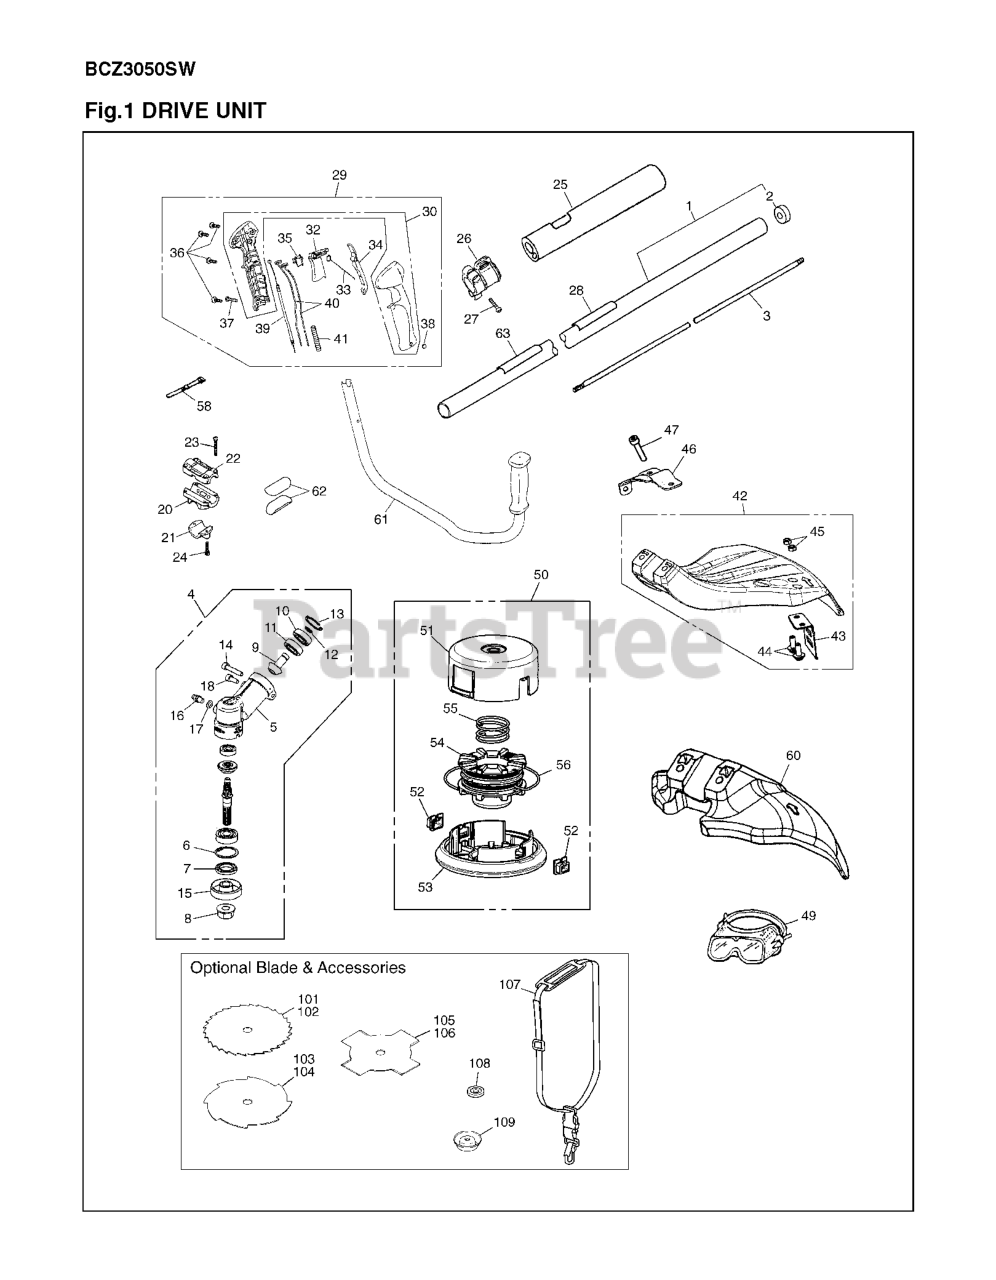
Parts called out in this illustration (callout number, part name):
1	PIPE COMP
4	GEARCASE
5	GEARCASE
6	RING,SNAP M26x1.2 RP-318013340
11	BALL BEARING
14	BOLT TORX
15	HOLDER(A)
18	BOLT, TORX
22	BRACKET-UP
25	PROTECTOR
26	HANGER COMP.
29	GRIP ASSY
30	HANDLE COMPLETE
42	GUARD ASSY
47	BOLT, TORX
49	GOGGLExxx (RPLS
50	4" TAP TRIMMER HEAD PT104
51	CASE (RPL T318915112)
53	COVER (RPLS T318915131)
54	HOLDER, CORD (RPLS T318915141)
56	CORD
58	BAND(KZC)
61	HANDLE-COMP
63	LABEL CAUTON FOR BC
101	Brushcutter Blade, 22 Tooth 9"
102	Brushcutter Blade, 24 Tooth 9"
103	BLADE, 8
104	Brushcutter Blade, 8 Tooth 9"
105	BLADE, 8
106	Brushcutter Blade, 4 Tooth 9"
107	STRAP ASSY
108	HOLDER (B)
